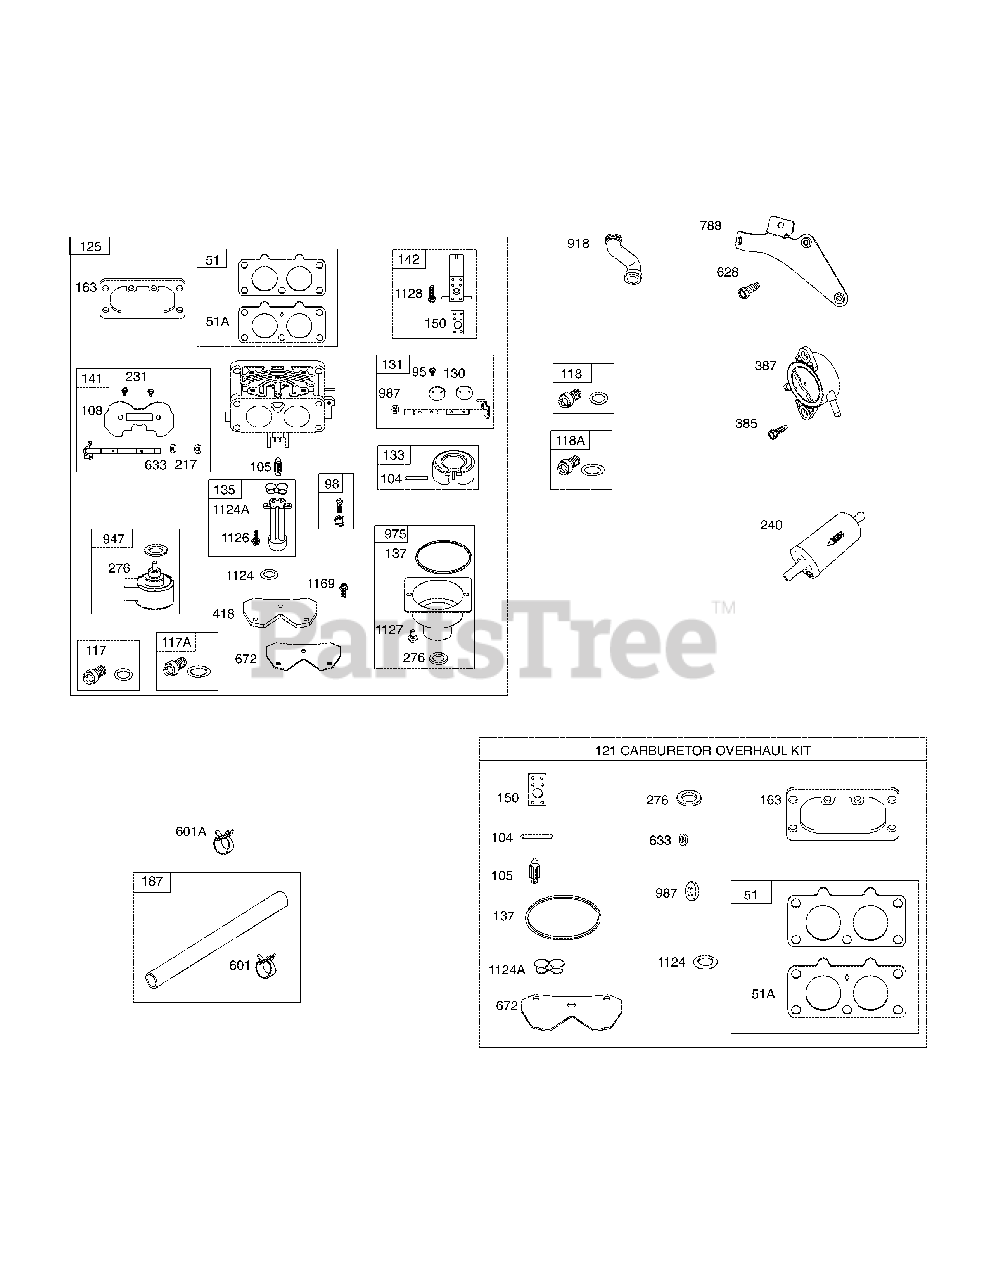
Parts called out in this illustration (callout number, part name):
1	Cylinder Assembly
2	Kit-Bushing/Seal (Magneto Side)
3	Oil Seal (Magneto Side)
4	EngineSump
5	Cylinder Head (Cylinder #1)
5A	Cylinder Head (Cylinder #2)
7	Cylinder Head Gasket
8	Breather Assembly
9	Breather Gasket
10	Screw (Breather Assembly)
11	Breather Tube
12	Crankcase Gasket
13	Screw (Cylinder Head)
15	Oil Drain Plug
16	Crankshaft
20	Oil Seal (PTO Side)
22	Screw (Crankcase Cover/Sump)
23	Flywheel
24	Flywheel Key
25	Piston Assembly (Standard)
25	Piston Assembly (.020" Oversize)
26	Ring Set (Standard)
26	Ring Set (.020" Oversize)
27	Piston Pin Lock
28	Piston Pin
29	Connecting Rod
32	Screw (Connecting Rod)
33	Exhaust Valve
34	Intake Valve
35	Valve Spring (Intake)
36	Valve Spring (Exhaust)
40	Valve Retainer
42	Valve Keeper
45	Valve Tappet
48	Short Block
50	Intake Manifold
51	Intake Gasket
51A	Intake Gasket
53	Stud (Carburetor)
54	Screw (Intake Manifold)
73	Rotating Screen
74	Screw (Rotating Screen)
75	Washer (Flywheel)
95	Screw (Throttle Valve)
98	Idle Speed Kit
104	Float Hinge Pin
105	Float Needle Valve
108	Choke Valve
117	Main Jet (Standard) (Left Jet)
117A	Main Jet (Standard) (Right Jet)
118	Main Jet (High Altitude) (Left Jet)
118A	Main Jet (High Altitude) (Right Jet)
121	Carburetor Overhaul Kit
125	Carburetor
130	Throttle Valve
131	Throttle Shaft Kit
133	Carburetor Float
135	Fuel Transfer Tube
137	Float Bowl Gasket
141	Choke Shaft Kit
142	Carburetor Nozzle
146	Timing Key
150	Nozzle Gasket
163	Air Cleaner Gasket
165	Nut (Ring Gear)
177	O-Ring Seal (Dipstick)
187	Fuel Line (Cut to Required Length)
188	Screw (Control Bracket)
192	Rocker Arm Adjuster
197	Screw (Back Plate)
209	Governor Spring (Yellow/Black)
211	Governed Idle Spring (Orange)
212	Throttle Link
216	Choke Link
217	Choke Return Spring
219	Governor Gear
220	Washer (Governor Gear)
221	Governor Cup
222	Control Bracket
227	Governor Control Lever
231	Screw (Choke Valve)
239	Oil Pressure Switch
240	Fuel Filter
250	Breather Retainer
252	Oil Collector
265	Casing Clamp
267	Screw (Casing Clamp)
276	Sealing Washer (Fuel Solenoid)
278	Washer (Governor Control Lever)
287	Screw (Dipstick Tube)
304	Blower Housing
305	Screw (Blower Housing)
305A	Screw (Blower Housing to Intake Elbow)
306	Cylinder Shield (Cylinder #2)
307	Screw (Cylinder Shield) (1.4-20 x 2.3)
309	Starter Motor
310	Screw (Starter Motor)
332	Nut (Flywheel)
333	Magneto Armature
334	Screw (Magneto Armature)
337	Spark Plug
358	Engine Gasket Set
385	Screw (Fuel Pump)
387	Fuel Pump
404	Washer (Governor Crank)
415	Plug (Oil Pressure Switch)
418	Carburetor Plate
431	Intake Elbow
445	Air Cleaner Cartridge Filter
447	Screw (Air Guide Cover) 10-24 x 7.16)
447A	Screw (Air Guide Cover)
467	Air Cleaner Knob
474	Alternator
501	Regulator
503	Starter Strap
505	Nut (Governor Control Lever)
510	Starter Drive
513	Drive Clutch
523	Dipstick
524	Dipstick Tube Seal
525	Dipstick Tube
526	Screw (Regulator)
544	Starter Armature
552	Governor Crank Bushing
552A	Governor Crank Bushing
562	Screw (Governor Control Lever)
573	Back Plate
579	Nut (Starter Cable)
601	Hose Clamp (Black)
601A	Hose Clamp (Green)
615	Governor Shaft Retainer
616	Governor Crank
617	O-Ring Seal (Intake Manifold) (Red)
628	Screw (Fuel Pump Bracket)
633	Choke Seal/Throttle Shaft
635	Spark Plug Boot
654	Nut (Carburetor)
668	Spacer (Rotating Screen)
668A	Spacer (Rotating Screen)
672	Carburetor Plate Gasket
691	Governor Shaft Seal
695	Screw (Ring Gear)
697	Screw (Drive Cap)
718	Locating Pin
741	Timing Gear
742	E-Ring Retainer (Governor Crank)
750	Screw (Oil Pump Cover)
783	Pinion Gear
788	Fuel Pump Bracket
789	Wiring Harness
798	Screw (Rocker Arm)
803	Starter Housing
847	Dipstick/Tube Assembly
851	Spark Plug Terminal
865	Air Guide Cover (Cylinder #1)
865A	Air Guide Cover (Valley)
868	Valve Seat
877	Alternator Wire/Connector
877A	Alternator Wire/Connector
883	Exhaust Gasket
914	Screw (Rocker Cover)
918	Vacuum Hose
943	O-Ring Seal (Oil Pump Cover)
947	Fuel Solenoid
965	Oil Pump Cover
967	Pre-Cleaner Filter
968	Air Cleaner Cover
975	Float Bowl
987	Throttle Shaft Seal
1005	Flywheel Fan
1013	Oil Filter Nipple
1017	Oil Pump Screen
1022	Rocker Cover Gasket
1023	Rocker Cover (Cylinder #1)
1023A	Rocker Cover (Cylinder #2)
1026	Push Rod (Exhaust)
1026A	Push Rod (Intake)
1027	Oil Filter
1029	Rocker Arm
1036	Emissions Label
1040	Trim Plate
1051	Retaining Ring (Starter Drive)
1059	Screw/Washer Kit (Alternator)
1070	Screw (Flywheel Fan)
1090	Brush Retainer
1095	Valve Gasket Set
1100	Rocker Arm Pivot
1119	Screw (Alternator)
1124	O-Ring Seal (Fuel Transfer Tube)
1124A	O-Ring Seal (Fuel Transfer Tube)
1126	Screw (Fuel Transfer Tube)
1127	Screw (Fuel Bowl)
1128	Screw (Carburetor Nozzle)
1169	Screw (Carburetor Plate)
1329	Replacement Engine
